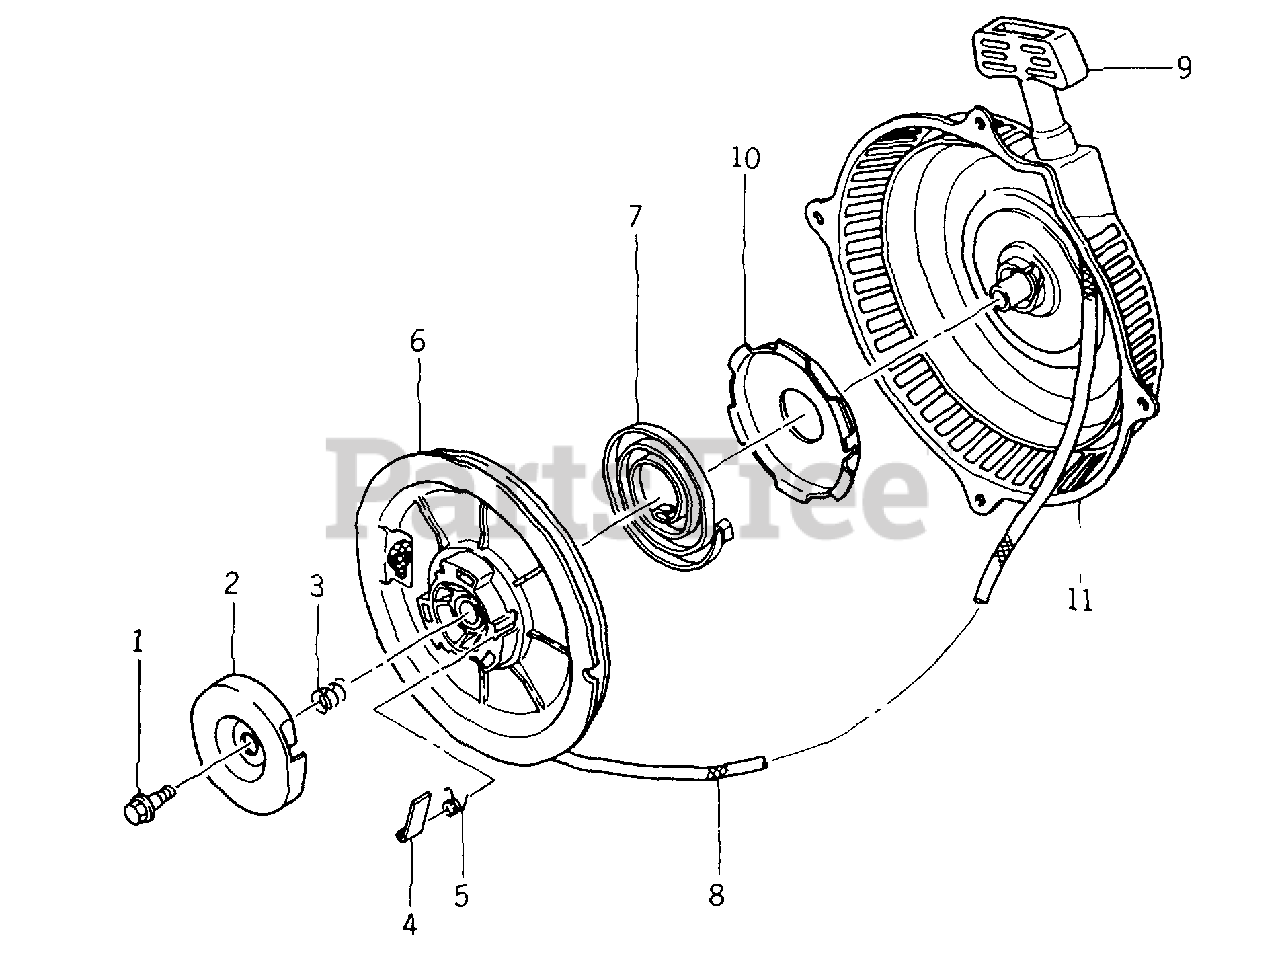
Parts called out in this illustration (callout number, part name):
1	BOLT
3	SPRING, return
4	PAWL
5	SPRING, return
6	REEL, recoil
7	SPRING, recoil
8	ROPE (6x1380)
9	GRIP
10	CASE, spring
11	CASE, recoil
